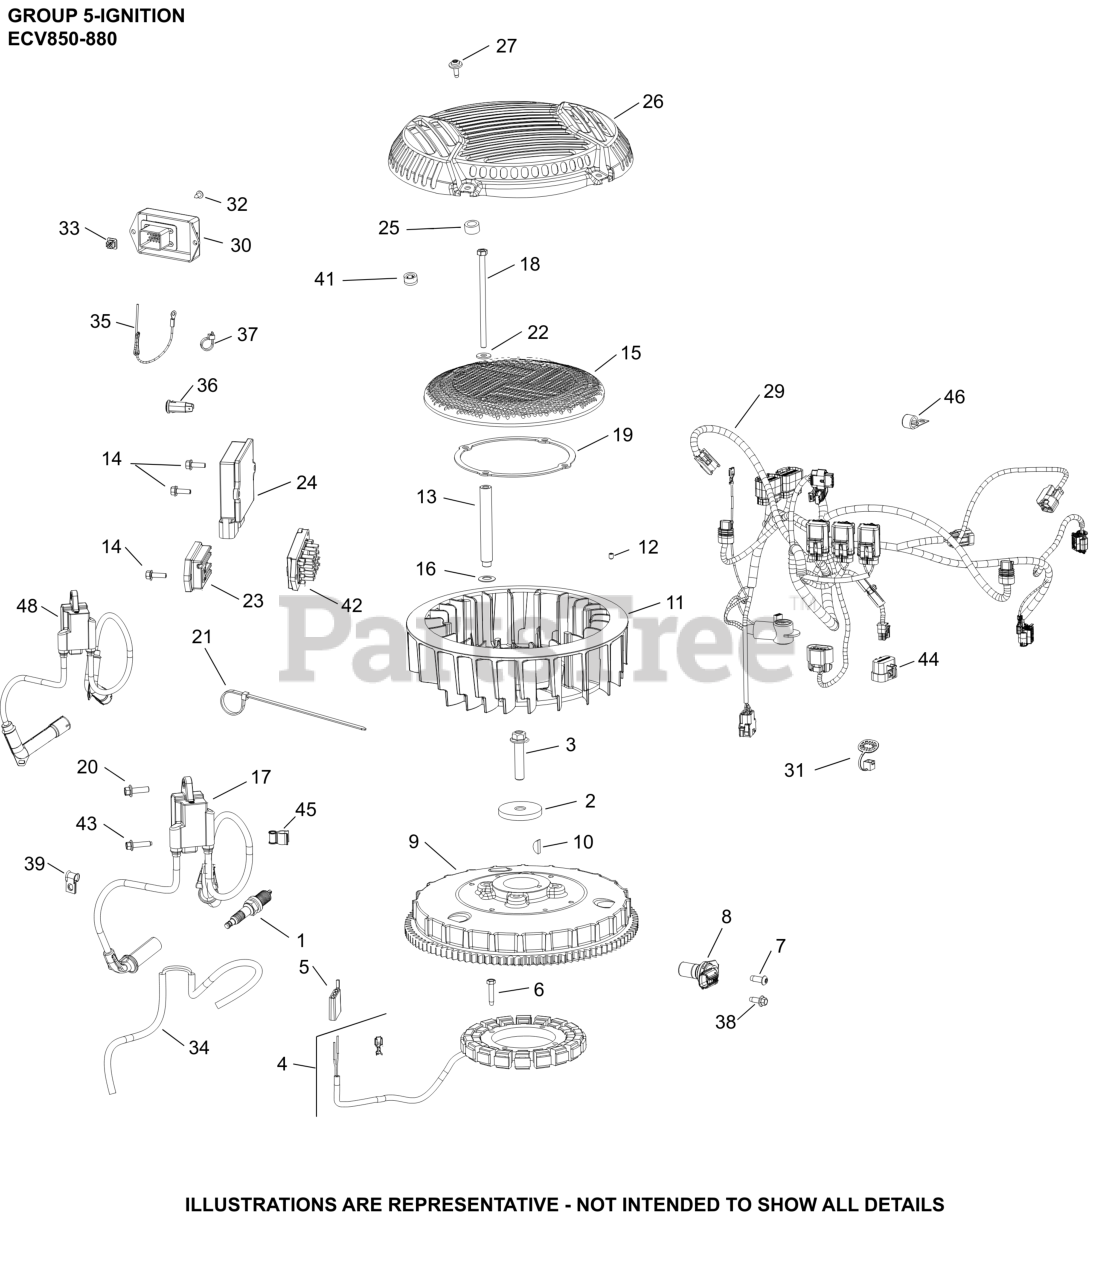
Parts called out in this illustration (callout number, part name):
1	PLUG, SPARK
2	WASHER, FLAT 13/32"
3	SCREW, FLG M10X1.5X45-USE 25 086 361-S
4	KIT, 25 AMP STATOR ASSY.
5	CONNECTOR
6	SCREW, THREAD FORMING
8	SENSOR, SPEED
9	FLYWHEEL, ASSEMBLY
10	KEY, 3/16" X 5/8"
11	FAN-(#6215706S)
12	SCREW, SKT SET #10-24X1/4"
13	SPACER GRASS SCREEN
14	SCREW, HVY FLG M5X.8X16
15	SCREEN, GRASS
16	WASHER, SPRING 10 MM
17	COIL, IGNITION DUAL OUTPUT
18	SCREW, HEX HEAD
19	RING, SUPPORT
22	WASHER, FLAT 1/4" (O.D. 5/8")
24	MODULE, ECU-USE 19 584 48-S
26	GUARD, GRASS SCREEN (METAL)
27	SCREW, SEMS
29	HARNESS, WIRING ASSEMBLY - EFI
31	CAP, CONNECTOR
38	SCREW, THREAD FORMING
42	REGULATOR, RECT (20-30AMP, FW W/OVP)
43	SCREW, FLG M6X1.0X25
46	CLIP, CABLE (KM)
